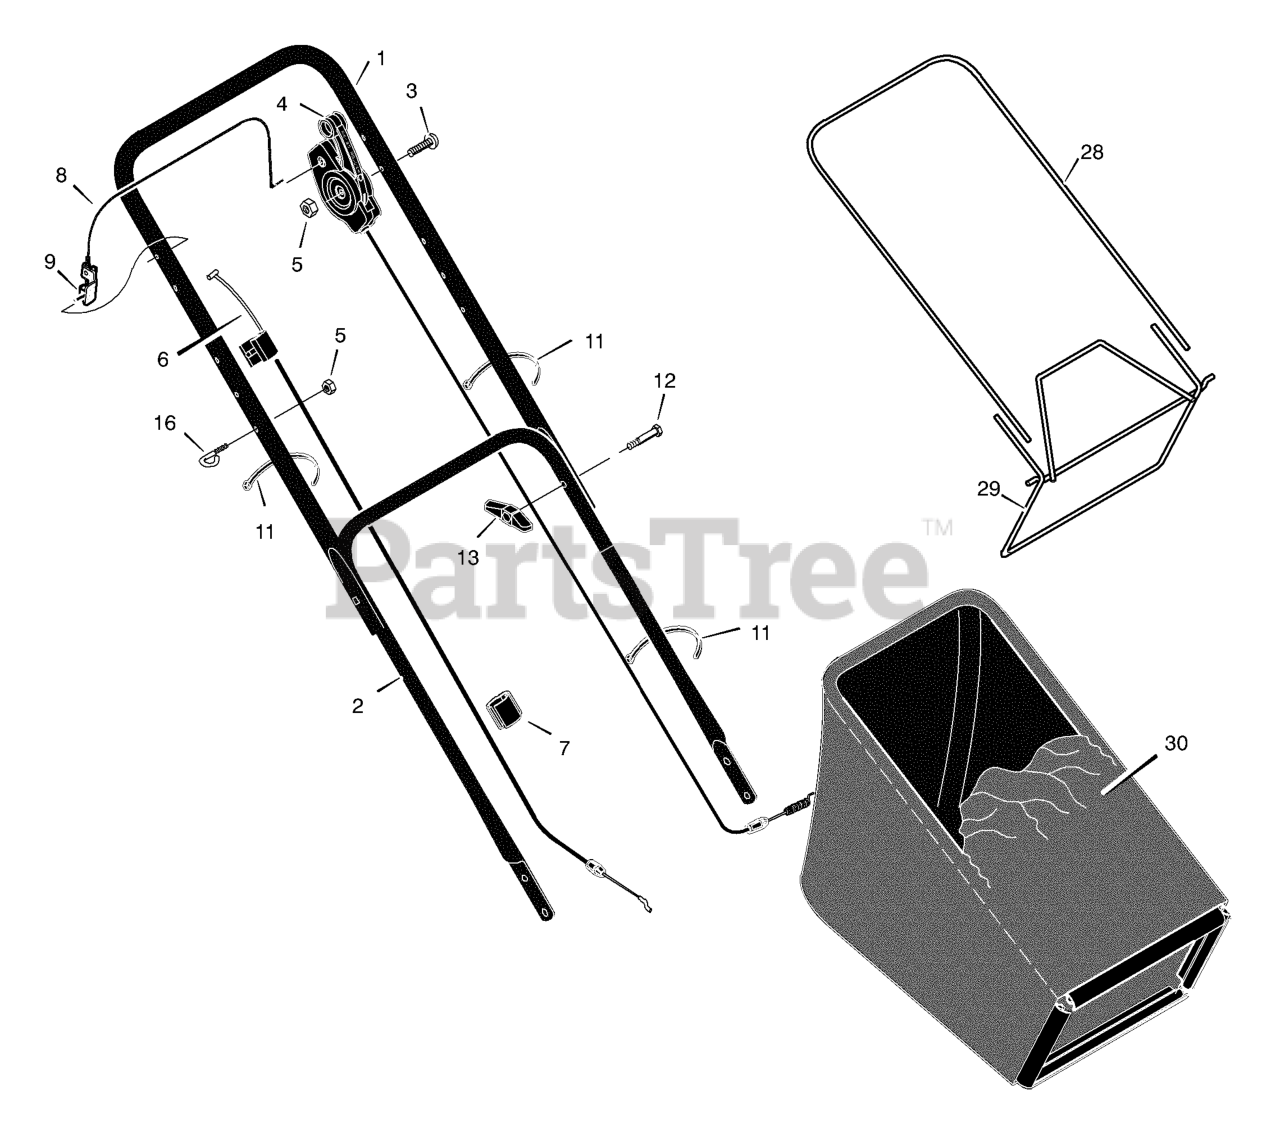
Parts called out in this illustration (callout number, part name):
1	Handle, Upper (Gray)
2	Handle, Lower (Gray)
4	Control, Drive
5	Locknut
6	Cable, Stop
7	Fastener, Cable
8	Engine Stop Lever
9	Bracket, Stop Lever
11	Fastener, Cable
13	Knob
16	Guide, Rope
28	Frame, Top
29	Frame Assembly
30	Bag, Cloth
